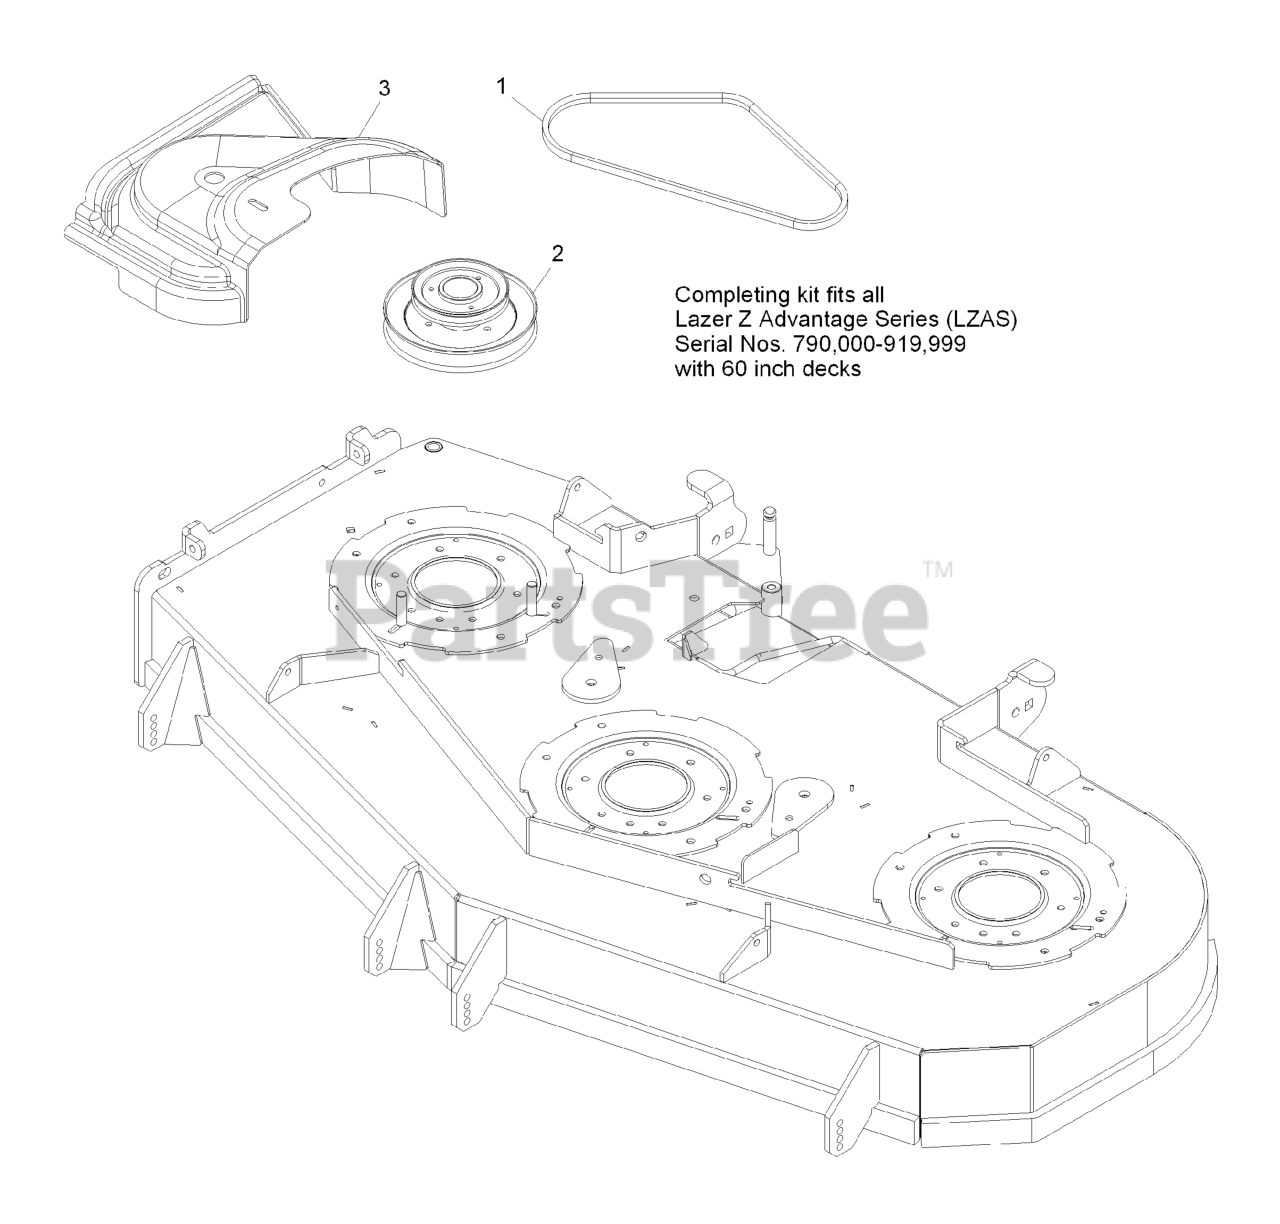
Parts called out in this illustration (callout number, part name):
1	BELT, BLOWER DRIVE 60
2	JACKSHAFT,UV DRIVE 604
3	COVER,BELT UV 60
